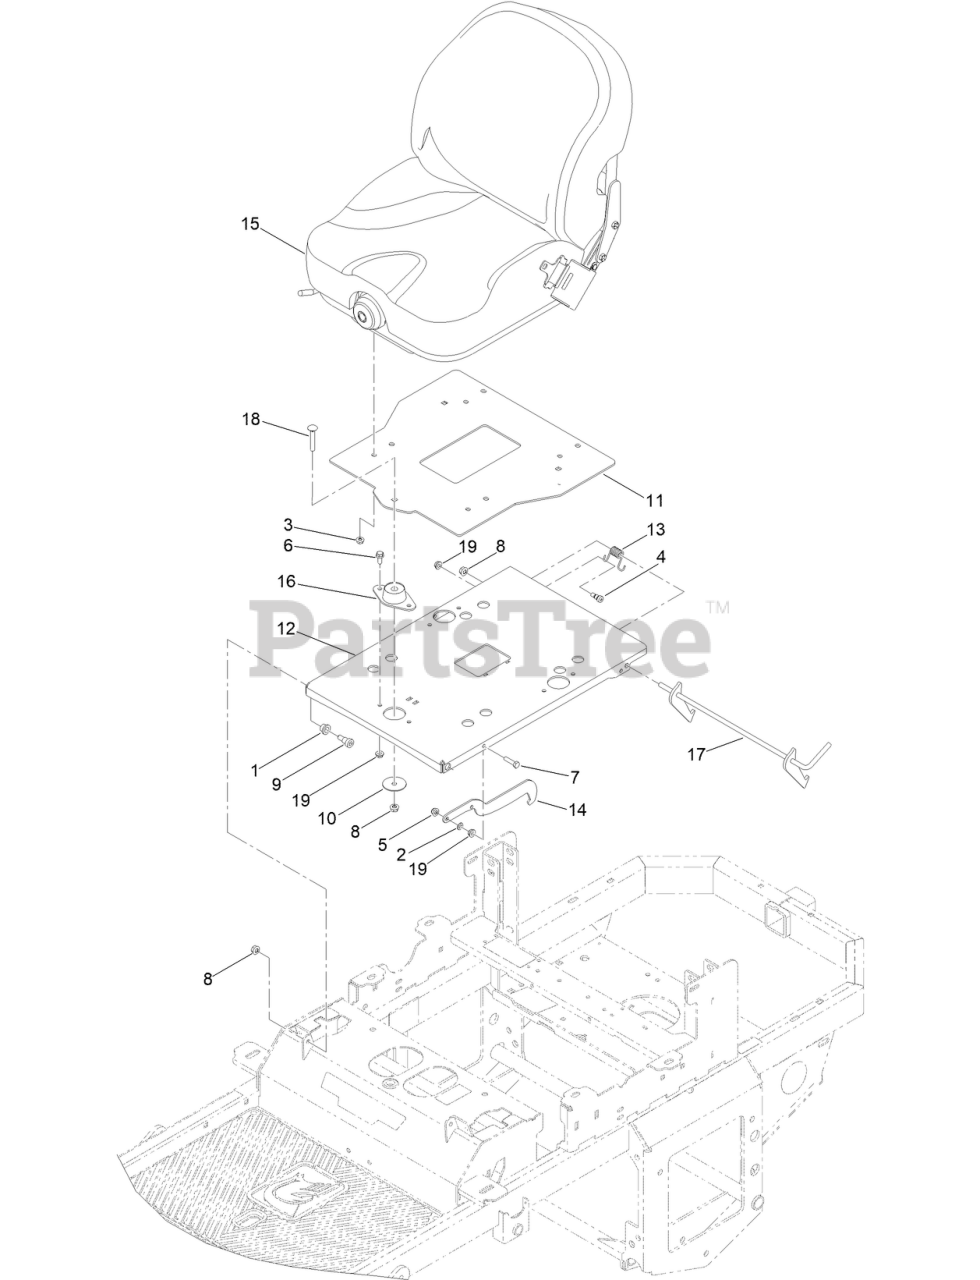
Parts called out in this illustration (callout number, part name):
1	1/2IN ID X 5/8IN OD X 1/2IN FLANGE BUSH
2	.312IDX.625ODX.062 THK THRUST BRG OI BRZ
3	5/16-18 NYLON INSERT FLANGE L/NUT ZC
4	SCREW-HSH
5	NUT-HF, NI
6	SCREW-HHF
7	SCREW-HH
9	1/2 X 1/2 SOCKET SHOULDER BOLT ZC YELLOW
10	3/8 X 2IN OD FENDER WASHER YZ
11	2019 UPGRADE SEAT PLATE PAINT
12	ASM, PLATE-SEAT BASE UPGRADE W/ DECALS
13	MWR SEAT LATCH SPRING
14	MWR SEAT LATCH HOOK PAINT
15	2019 FULL SUSP SEAT
16	FLOATING SEAT DAMPER-STIFFER
17	MWR SEAT LATCH RELEASE ASSY ABC
18	SCREW-CARR
